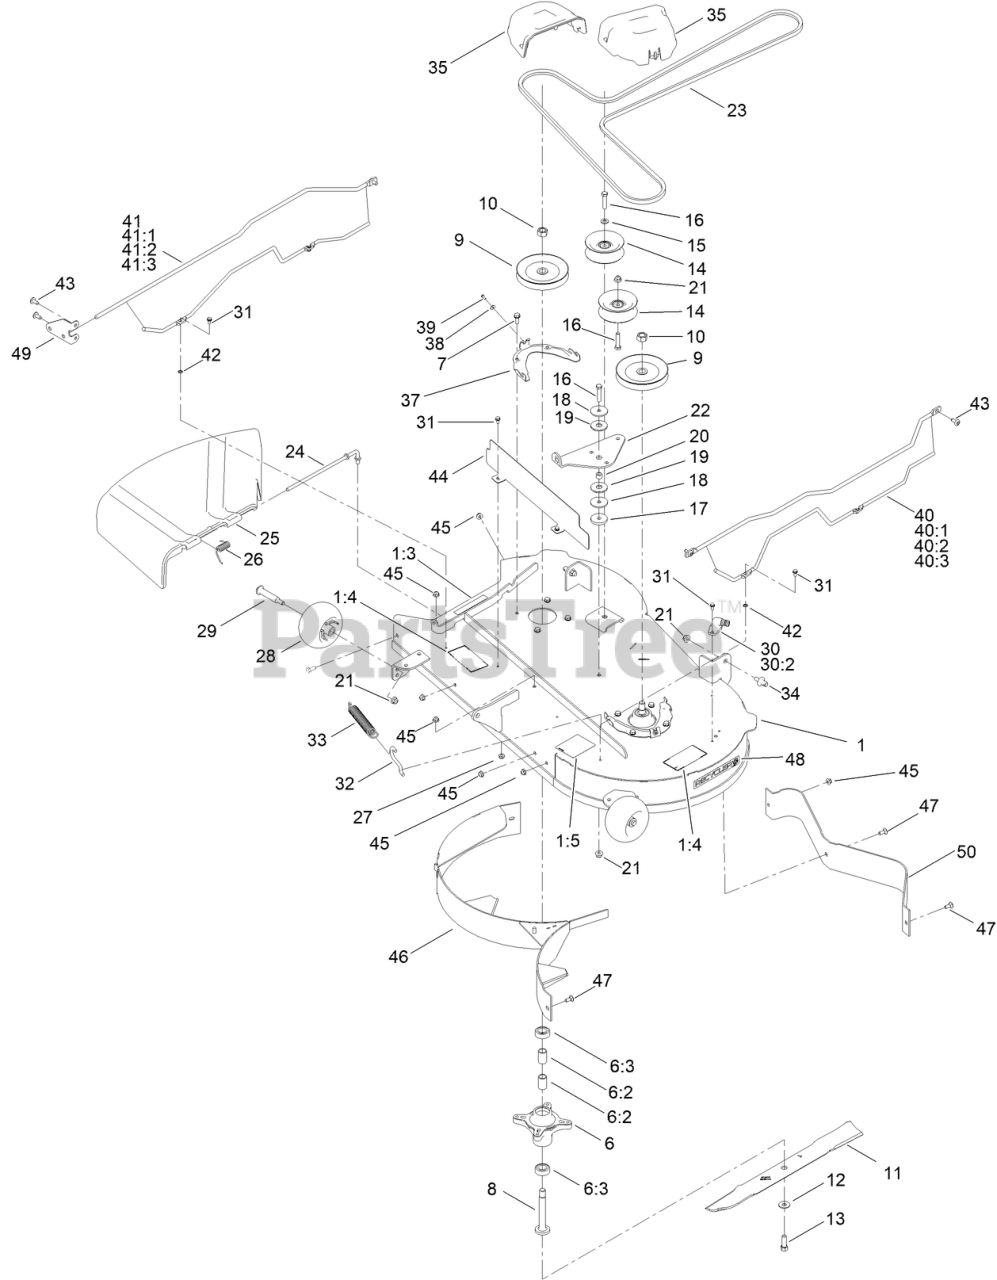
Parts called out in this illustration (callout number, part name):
1	42IN DECK AND DECAL ASM
1:3	DECAL-DANGER
1:4	DECAL-DANGER, DECK
1:5	DECAL-ROUTING, BELT
6	SPINDLE ASM
6:2	SPACER
6:3	BEARING-BALL
7	SCREW-TAPTITE
8	SHAFT-SPINDLE
9	Pulley
10	Nut-Hex
11	BLADE-MULCH
12	WASHER-BELLEVILLE
13	SCREW-HH
14	PULLEY-IDLER, FLAT
15	WASHER-FLAT
16	SCREW-HH
17	WASHER-PLAIN
18	Washer
19	WASHER-FRICTION, COMPOSITE
20	SPACER
21	NUT-HF, NI
22	ARM-IDLER
23	V-BELT
24	ROD-PIVOT
25	DEFLECTOR-DISCHARGE
26	SPRING-TORSION
27	NUT-HEX
28	ROLLER-SCALP, ANTI
29	BOLT-SHOULDER
30	FITTING-WASHOUT
30:2	O-RING
31	SCREW-HWH
32	HOOK-RETURN SPRING
33	SPRING-EXTENSION
34	PIN-DECK
35	COVER-BELT
37	BRACKET-COVER, BELT
38	WASHER-PLAIN
39	SCREW
40	LEFT GUARD ASM
40:1	GUARD-LEFT
40:2	ROD-TOP, LEFT
40:3	ROD-SUPPORT, LOWER
41	RIGHT GUARD ASM
41:1	GUARD-RIGHT
41:2	ROD-SUPPORT, LOWER
41:3	ROD-TOP, RIGHT
42	NUT-RETAINING
44	SHIELD-FROUNT
45	NUT-HF
46	BAFFLE-RECYCLING
47	BOLT-CARR
48	DECAL-RECYCLER
49	PLATE-MOUNT, GUARD
50	DEFLECTOR
